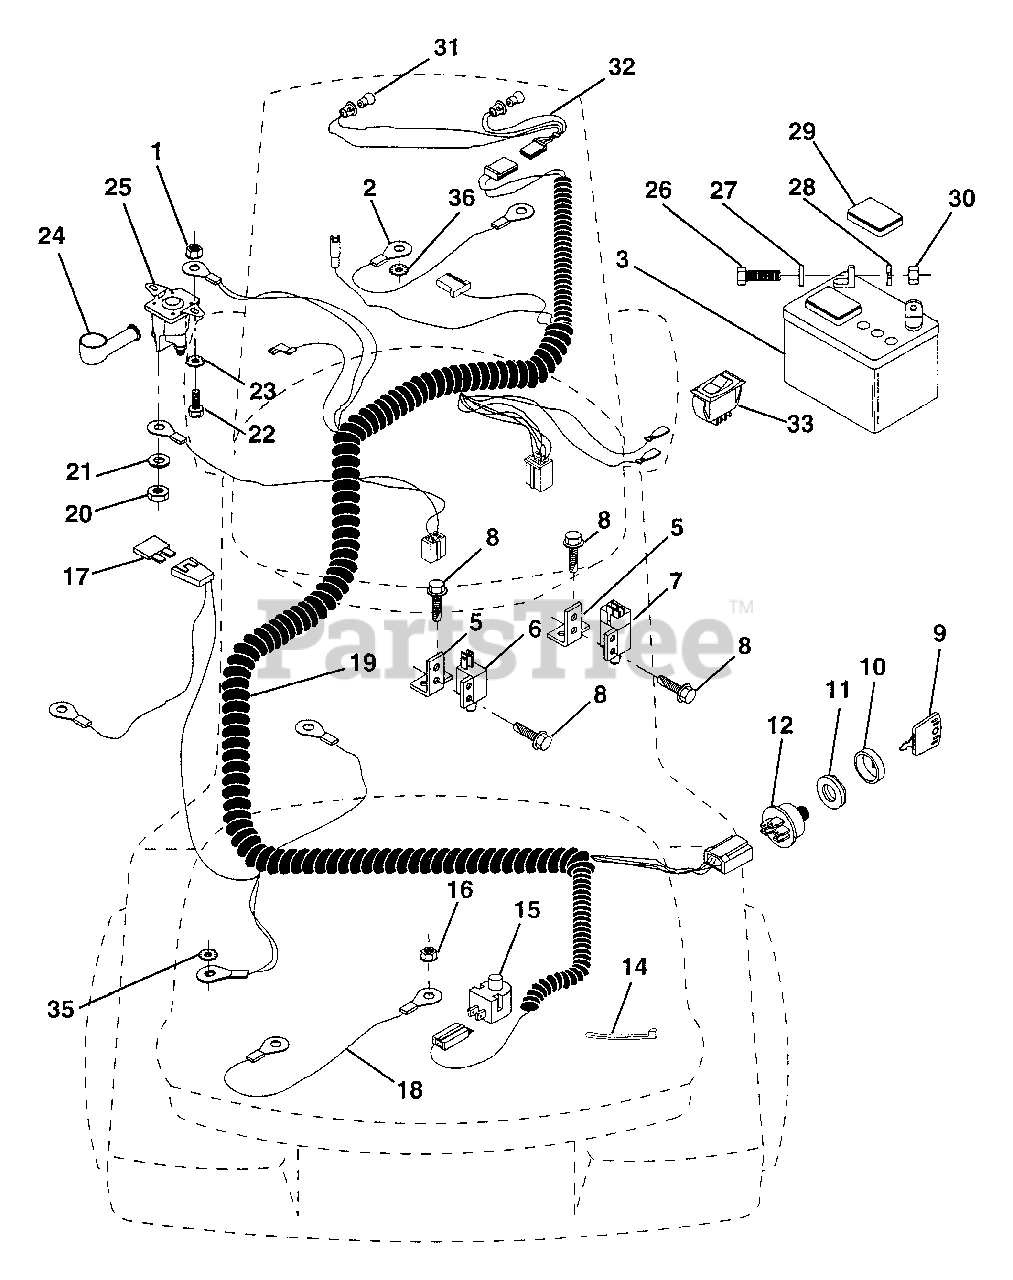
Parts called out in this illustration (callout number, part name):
1	Nut, Hex Keps 1/4-20
2	Assembly, Cable
3	Battery
5	Bracket, Switch
6	Switch, Interlock (2-terminal)
7	Switch, Interlock (4-terminal)
8	Screw, Hex Hd. Tap #10-24 x 1/2
9	Key, Molded
10	Cover, Key Ignition
11	Nut, Ignition
12	Switch, Ignition
14	Tie, Cable
15	Switch, Plunger
16	Nut, Hex, Keps 5/16-18
18	Assembly, Cable
19	Harness, Ignition
20	Nut, Hex Jam 1/4-20
21	Washer, Lock 1/4
22	Bolt, Fin. Hex 1/4-20 UNC x 1/2 Gr. 5
23	Washer, Lock Ext. Tooth 1/4
24	Cover, Terminal
25	Solenoid
26	Bolt, Hex Hd. 1/4-20 UNC x 3/4
27	Washer 9/32 x 5/8 x 16
28	Washer, Lock 1/4
29	Cap, Battery
30	Nut, Fin. Hex 1/4-20 UNC
31	Bulb, Light
32	Harness, Headlight
33	Switch, Light
35	Washer Lock Ext. Tooth 3/8
36	Washer Lock Inter. Tooth 1/4
